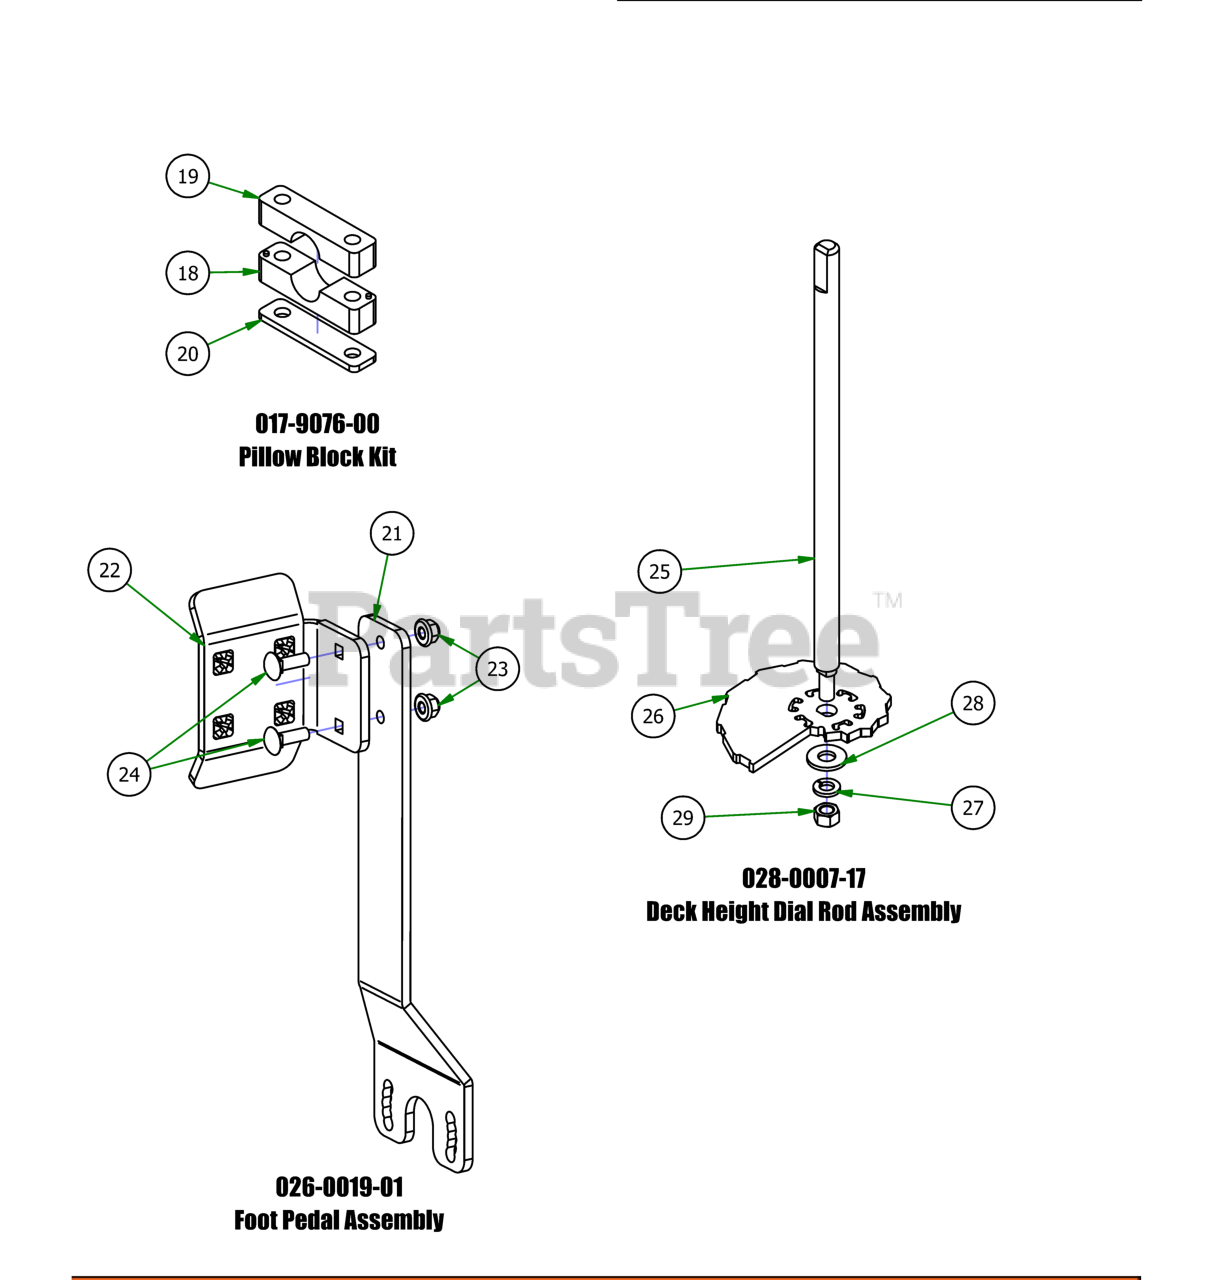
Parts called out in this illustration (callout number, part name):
18	Pillow Block MZ male
19	Pillow Block MZ female
20	Pillow Block Strap
21	2017 MZ/ZT Deck Pedal Lever
22	2017 MZ/ZT Shallow Foot Pedal
23	5/16" Nylon Flange Nut
24	5/16" x 1" Carriage Bolt
25	2017 Deck Height Dial Rod MZ
26	2017 MZ/ZT Cam Plate
27	3/8" Lock Washer
28	3/8" Flat Washer
29	3/8" Fine Threaded Jam Nut
